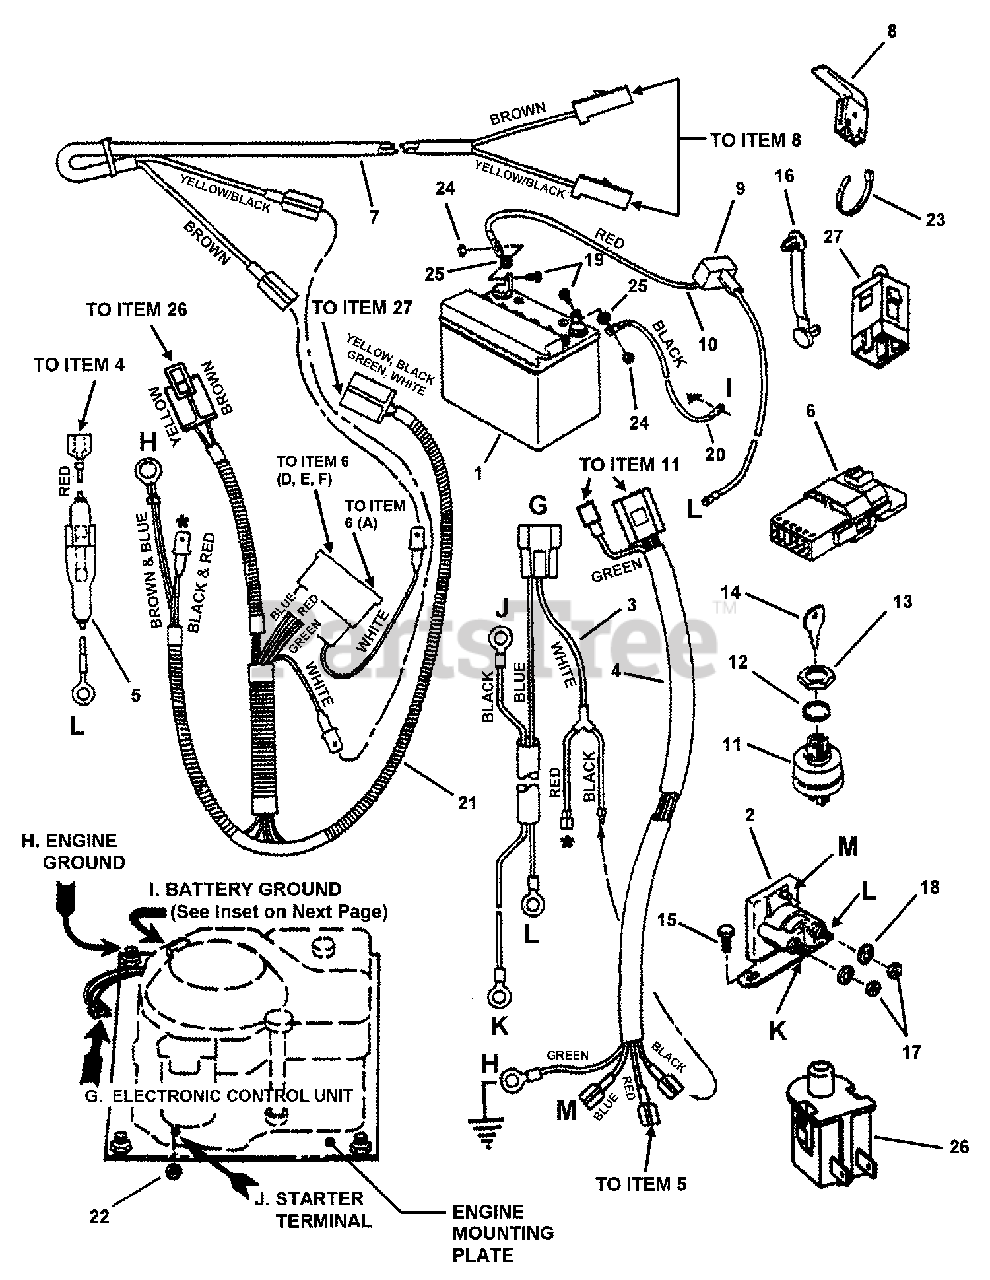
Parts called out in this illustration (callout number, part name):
1	KIT, Battery, 12 Volt, 220CCA, Dry Charge
2	SOLENOID, Super-Trombetta
3	HARNESS, Starter Wiring (Kohler Engines)
4	HARNESS, Ignition Wiring (15HP Kohler Engines)
5	HOLDER, Fuse (Includes Fuse)
6	INTERLOCK MODULE, Briggs & Kohler
7	HARNESS, (Deck Interlock Wiring)
8	SWITCH, Deck Interlock (NO)
9	COVER, Battery Cable
10	WIRE, Positive (Red, 17" long)
11	SWITCH, Ignition, 4 Terminal, Indak
12	WASHER, 5/8" Internal Tooth Lock
13	NUT, 5/8-32 Hex
14	IGNITION KEY, Pair
14	KEYS, Blister Pk (KIDS+MWRS DON'T MIX) English/French (set of two, one coated)
15	SCREW, 1/4-20 x 1/2" Hex Washer Self-Tap
16	CABLE TIE, 3.19" long
17	NUT, 1/4-20 Hex
18	WASHER,1/4" Internal Tooth Lock
19	SCREW, 1/4-20 x 5/8" Hex Head Cap, GR 5
20	WIRE, Negative, Black (15" long)
21	HARNESS, Operator Presence Control (OPC) Wire
22	NUT, 1/4-20 Hex, GR 5 or B
23	CABLE TIE, 7"
24	NUT, 1/4-20 Hex Center Lock, GR 5 or B
25	RETAINER, 1/4" Bolt
26	SWITCH, Seat (NC)(Gray)
27	SWITCH, Operator Presence Control (OPC) Traction (NC/NO)
